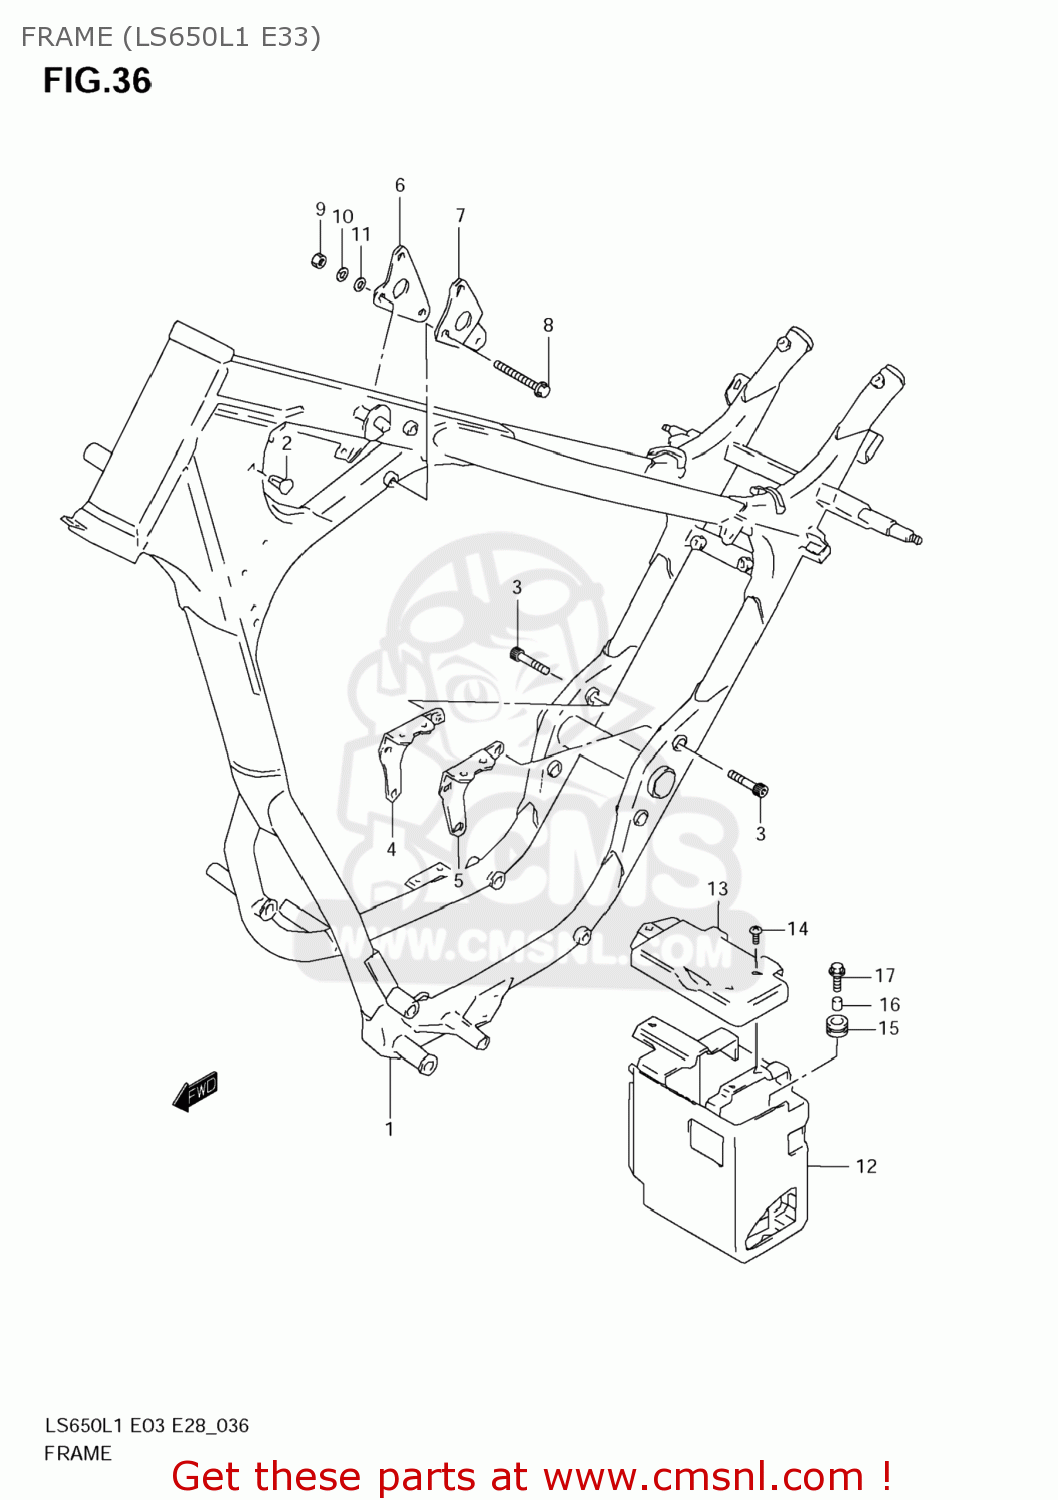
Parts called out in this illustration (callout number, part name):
1	FRAME(BLACK)
2	CLIP
3	BOLT(8X40)
4	PLATE,ENGINE MOUNT NO.4,R
5	PLATE,ENGINE MOUNT NO.4,L
6	PLATE,ENGINE MOUNT NO.5,R
7	PLATE,ENGINE MOUNT NO.5,L
8	BOLT(8X72)
9	NUT
10	WASHER,LOCK
11	WASHER
12	HOLDER,BATTERY
13	COVER,BATTERY
14	SCREW
15	CUSHION
16	SPACER(6.5X9X7.2)
17	BOLT(6X20)
